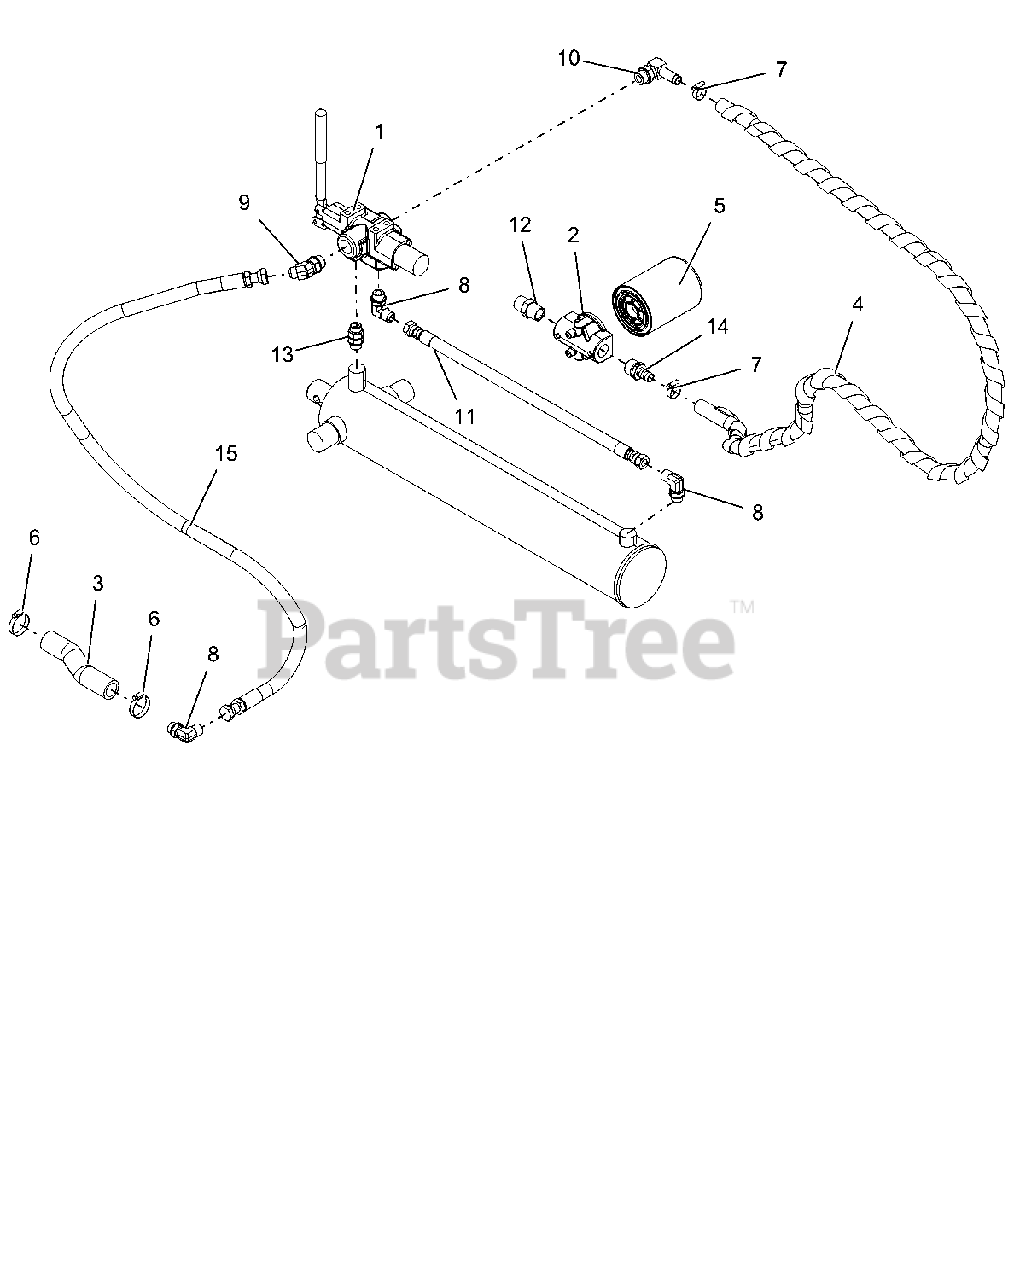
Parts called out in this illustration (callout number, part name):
1	VALVE CONTROL-SPLITTER
2	HEAD,FILTER-3/4 NPT BYPASS
3	HOSE, HYD - SUCTION 7.375"
4	HOSE, HYD-RET 801-10 WP 74"
5	FILTER,HYDRAULIC OIL-NO BYPASS
6	CLAMP-HOSE 1.50X.81X1.42
7	CLAMP,.88 DIA. HOSE
8	FTG,HYD 6801-8-8
9	FTG,HYD 6802-8-10
10	FTG,HYD 4601-10-10
11	HOSE, HYD - 22"
12	FTG,HYD 5404-12-12
13	FTG, HYD - STR 08MAORB-08MORB
14	FTG,HYD STRAIGHT 10-12
15	HOSE, HYD - 58"
